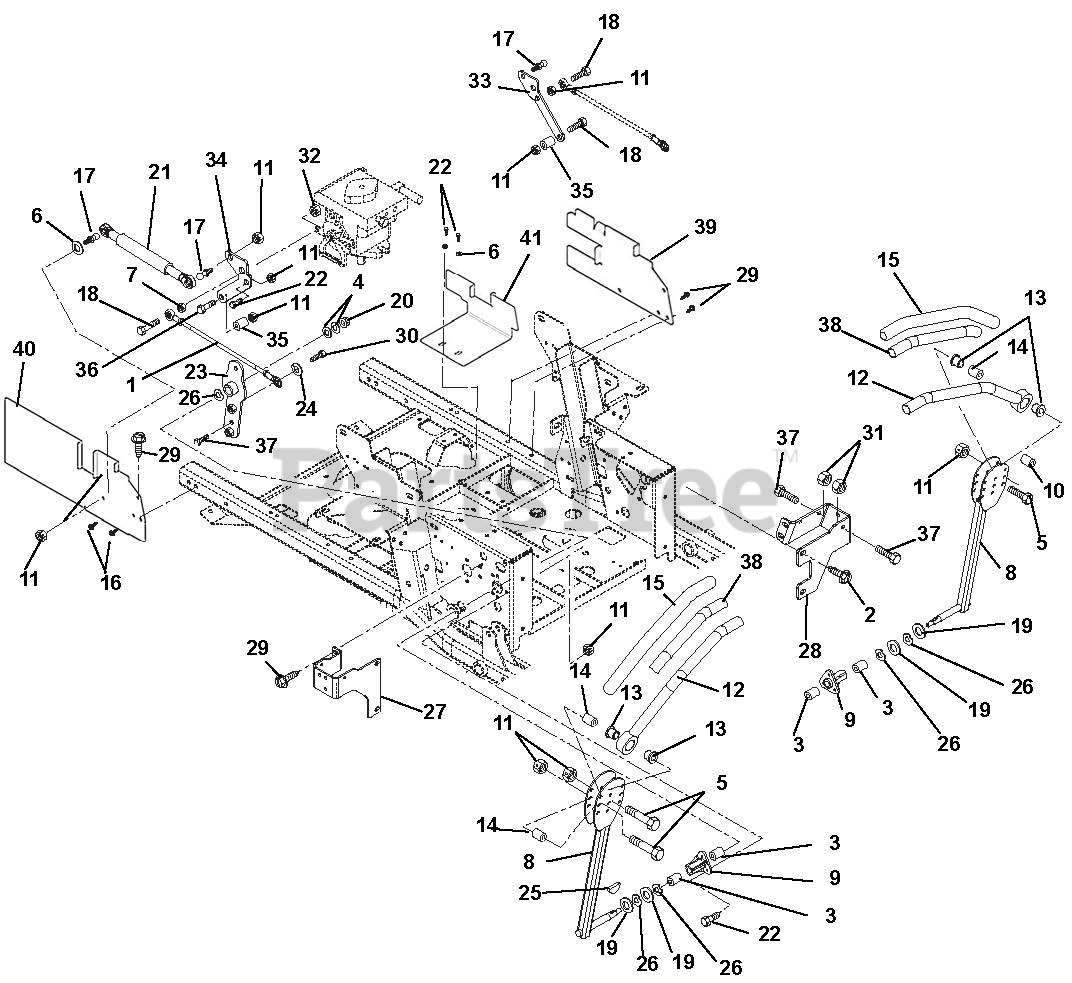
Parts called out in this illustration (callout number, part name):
1	Assembly, Steering Rod .38 Rod x 7.60
2	Screw, Tapping .Hex Washer Head 38-16 x .75
3	Bushing .625 x .75 x .50
4	Washer, Flat Steel .403 x .812 x .065
5	Bolt, Hex .31-18 x 1.75 Grade 5
6	Washer, Flat Steel .344 x .688 x .065
7	Nut, Hex .38-16
8	Control Arm
9	Bushing, Flange
10	Bushing, Eccentric .31 x .75 .97
11	Nut, Locking Top Flange .31-18
12	Handle Weldment, Left Hand
12	Handle Weldment, Right Hand
13	Bushing, Flange Nylon .762 x 1.48 x .44
15	Grip, Handlebar
16	Screw, Tapping Hex Washer Head .31-18 x .50
17	Stud, Ball
18	Bolt, Hex .38-16 x 1.50 Grade 5
19	Washer, Flat Steel .63 x 1.005 x .062
20	Nut, Locking Top Flange .38-16
21	Damper, Control
22	Bolt, Hex .31-18 x .75 Grade 5
23	Weldment, Pivot Arm
24	Washer, Locking .38 x .094 Regular
25	Key, Woodruff .13 x .63
26	Washer, Wave
27	Stop, Steering Right Hand
28	Stop, Steering Left Hand
29	Screw, Tapping Hex Washer Head .38-16 x .50
30	Bolt, Hex .38-16 x 1.25 Grade 5
31	Nut, Hex Jam .375-16
32	Nut, Locking Center .38-16
33	Bracket, Left Hand
34	Bracket, Right Hand
35	Spacer .318 x .43 x .375
36	Bolt, Hex .31-18 x 1.25 Grade 5
37	Bolt, Hex .375-16 x 1.75 Full Thread
38	Tube, .88ID x 1.00OD x 10.75
39	Bracket, Dampener Debris Shield Left Hand
40	Bracket, Dampener Debris Shield Right Hand
41	Shield, Debris Lower
